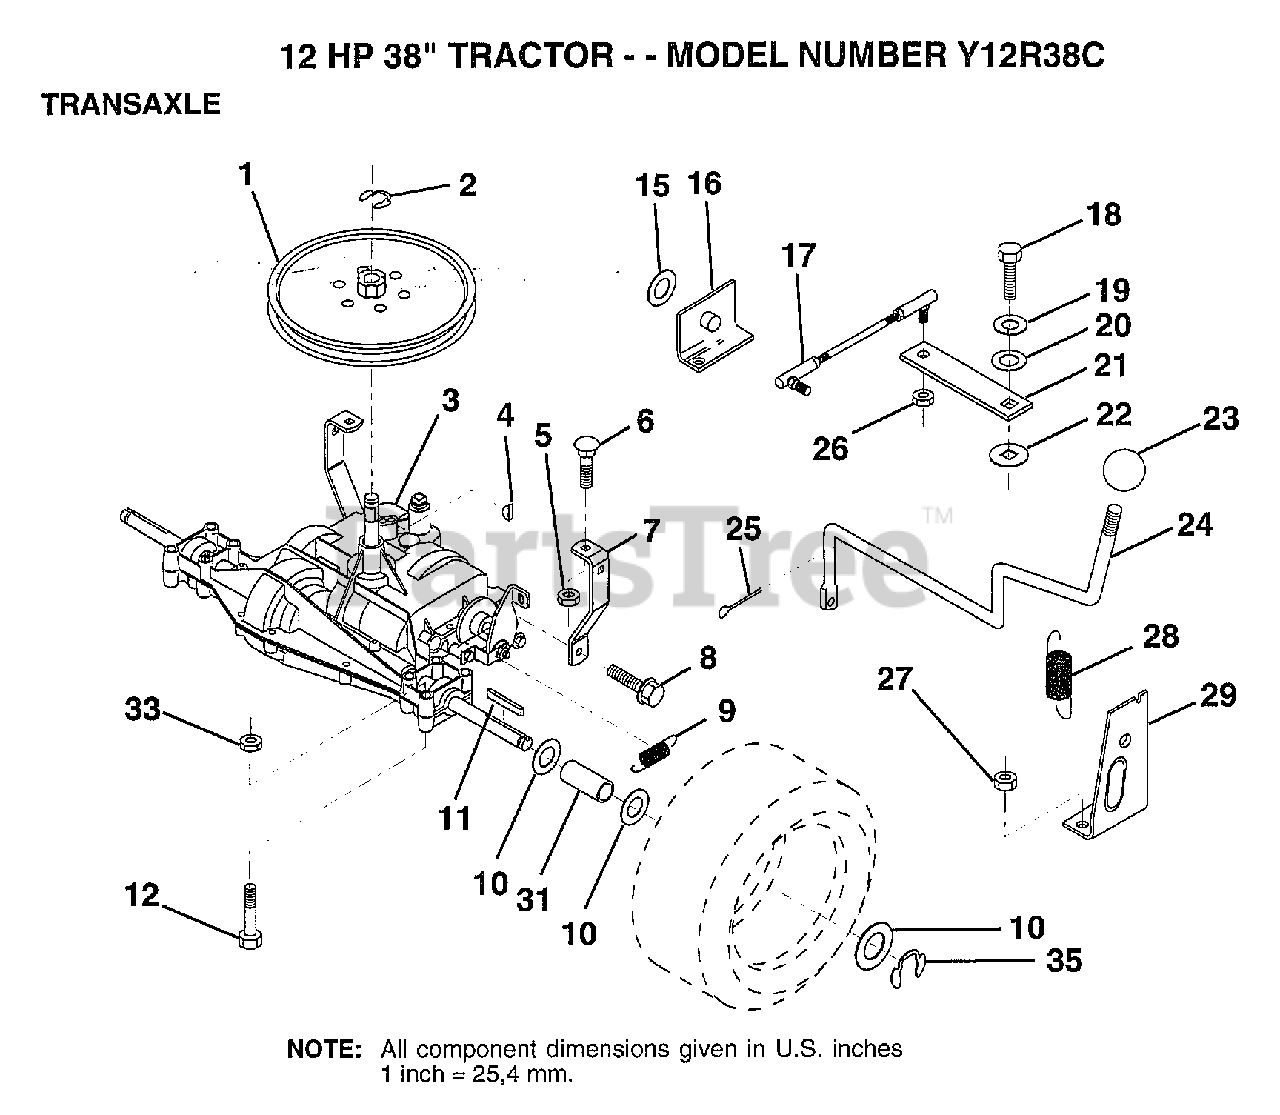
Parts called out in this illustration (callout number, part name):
1	PULLEY
5	NUT
6	BOLT
7	"STRAP,TORQUE"
8	SCREW
10	WASHER
11	SQUARE KEY
12	BOLT
16	"SUPT,HDLE SHT LH"
17	"LINK,SHIFT"
19	LOCKWASHER
20	WASHER LT
21	"ARM,SHIFT"
22	WASH-SHFT PLT LT
23	KNOB.DUCKHEAD.1/2
24	"ROD,SHIFT"
25	PIN COTTER 1/8
26	NUT.LOCK.5/16-24
28	"SPRING,EXT"
29	"SUPT,HDLE RH"
31	SPACER LT
35	E-RING LT
